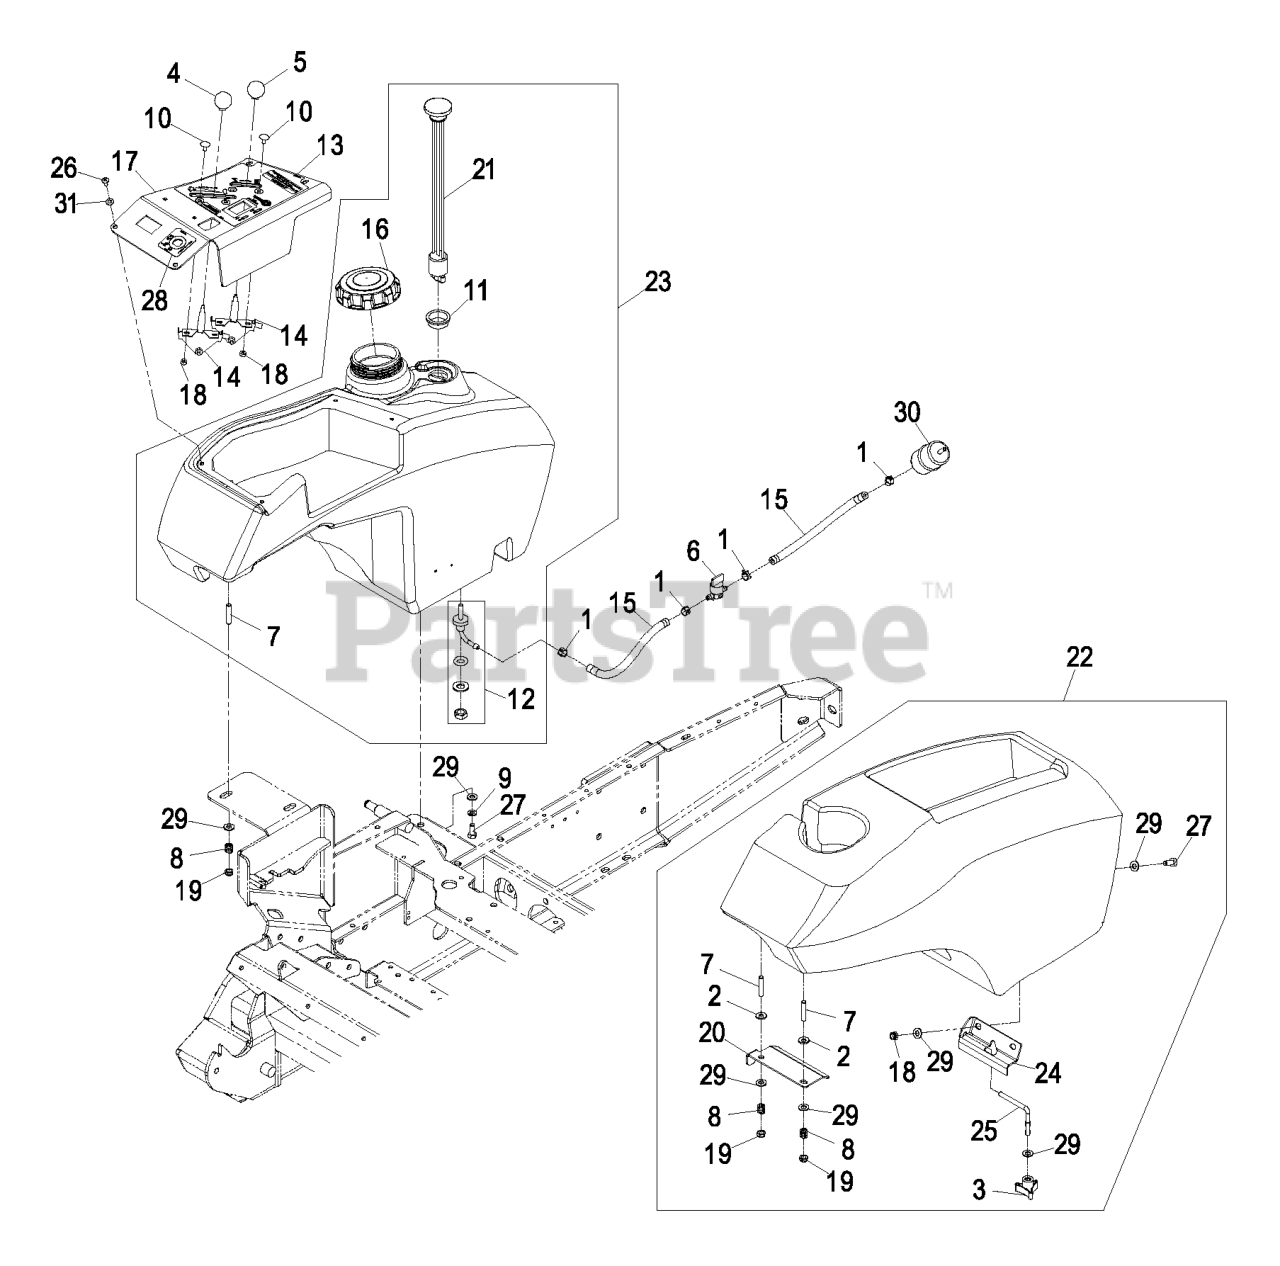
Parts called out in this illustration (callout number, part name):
2	WASHER-SPRING
3	KNOB-3 PRONG
4	KNOB-BALL
5	KNOB-BALL, BLACK
6	VALVE-FUEL
7	STUD
8	SPRING-TANK, FUEL
9	WASHER-LOCK
10	BOLT-CARR
11	CONTACT ORDER SERVICES
12	FITTING-FUEL, BULKHEAD
13	DECAL,CONSOLE FMZ A/C
14	CABLE-THROTTLE
15	HOSE-FUEL
16	CAP-FUEL, GAS
18	NUT-LOCK, NI
19	NUT-LOCK, NI
20	HOOK,FENDER (PLATED)
21	Gauge, Fuel
22	ASM,FENDER FMZ
24	BRACKET,FENDER
25	BOLT,FENDER
26	SCREW-PTH
27	SCREW-HH
28	DECAL,IGNITION
29	WASHER-PLAIN
30	Kohler Part No. 2405010 Fuel Filter
31	WASHER-SPRING
